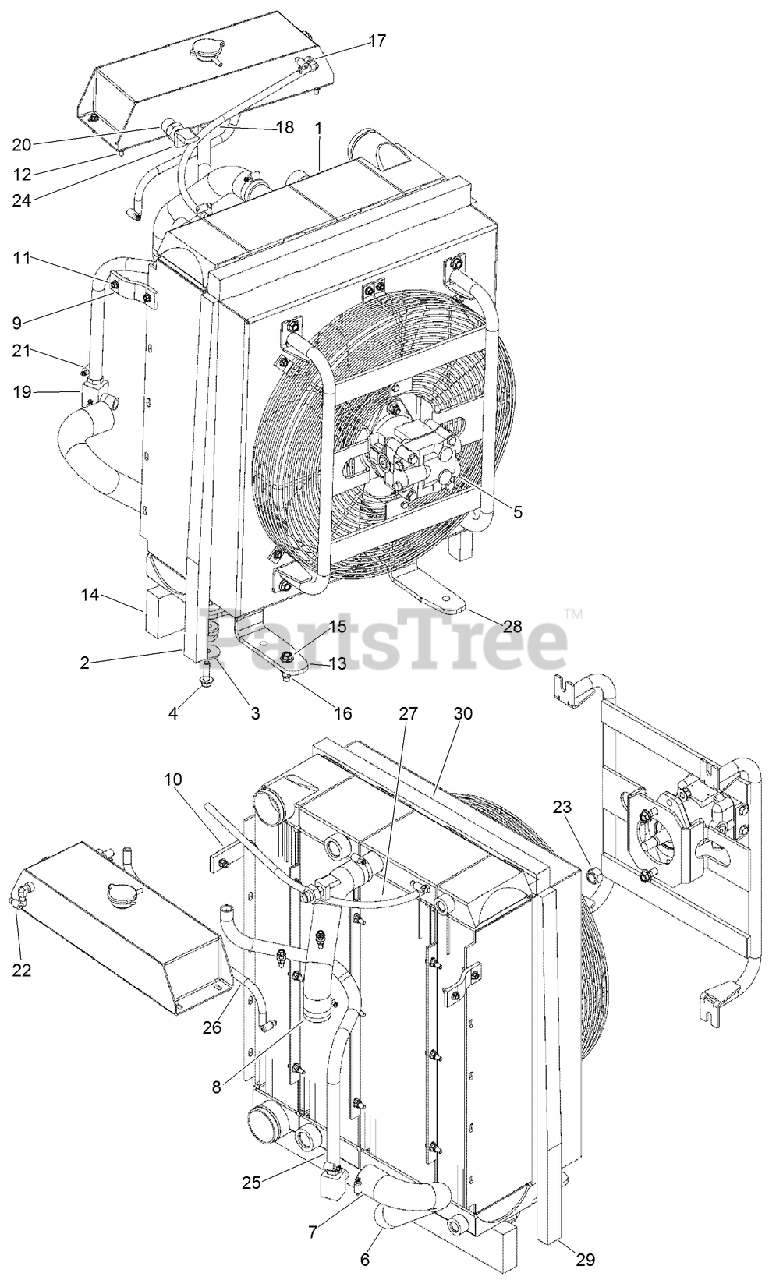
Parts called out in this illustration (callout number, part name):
1	ASSEMBLY - Engine Cooling Package
2	ISOLATOR-MOUNT, RUBBER
3	WASHER-FLAT
5	HYD MOTOR ASM
6	HOSE - Radiator, Lower
7	CLAMP-Hose Type F #32
8	HOSE - Radiator, Upper
9	STRAP - Radiator Mounting
10	STRAP - Radiator Mounting
11	SCREW, METRIC FLANGE FULL - M8 x 25
12	NUT-TORQUE, PREVAILING
13	PLATE - Electrical Mount
14	FOAM - Insulation
15	SCREW-HHF
16	NUT-HHF, LOCK
17	ELBOW - 90 Hose Stem, 3/8 ID x 174 NPTF
18	STEM - Str Bead Hose 3/4 ID x 3/4 NPTF
19	ELBOW-STREET, 90 DEG
20	BUSHING - Reducer, Internal/External, NPT
21	CLAMP - Hose, Type F #20
22	CLAMP-HOSE
23	NUT - Lock, Stover
24	SENSOR-LEVEL, COOLANT
25	HOSE - Silicon
26	HOSE - Fuel
27	HOSE - Fuel
28	PLATE - Electrical Mount
29	FOAM - Baffle
30	FOAM - Baffle
